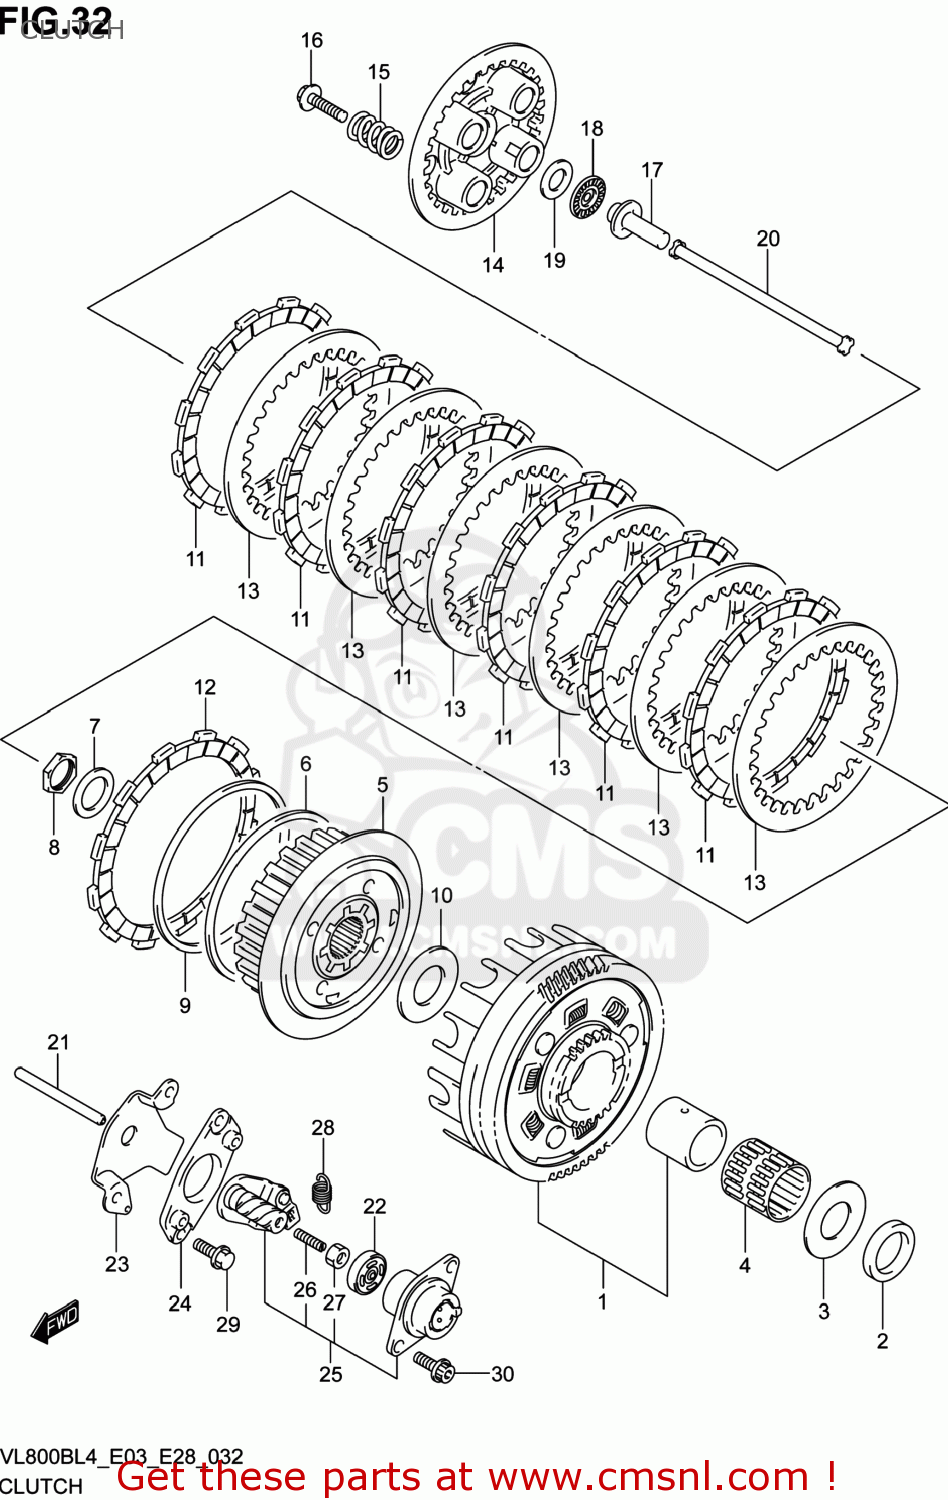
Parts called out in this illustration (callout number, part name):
1	GEAR ASSY,PRIMARY(NT:71)
2	SPACER(25X38X6.5)
3	WASHER(25X50X2.5)
4	BEARING(35X40X35.8)
5	HUB,CLUTCH SLEEVE
6	SEAT,WAVE WASHER(T:1.4)
7	WASHER
8	NUT
9	WASHER
10	WASHER(25X50X2.5)
11	PLATE,CLUTCH DRIVE (NAS)
12	PLATE,CLUTCH DRIVE(T:3.5) (NAS)
13	PLATE,CLUTCH DRIVEN(T:1.6) (NAS)
14	DISC,CLUTCH PRESSURE
15	SPRING,CLUTCH
16	BOLT(6X30)
17	PIECE,CLUTCH PUSH
18	BEARING(15X28X2)
19	WASHER(15.5X28X1)
20	ROD,CLUTCH
21	ROD,CLUTCH PUSH,L
22	SEAL,OIL(6X34X10.5)
23	RETAINER,CL PUSH ROD OIL SEAL
24	PLATE,CLUTCH RELEASE SCREW
25	SCREW ASSY,CLUTCH RELEASE
26	SCREW(6X25)
27	NUT
28	SPRING
29	BOLT
30	BOLT
